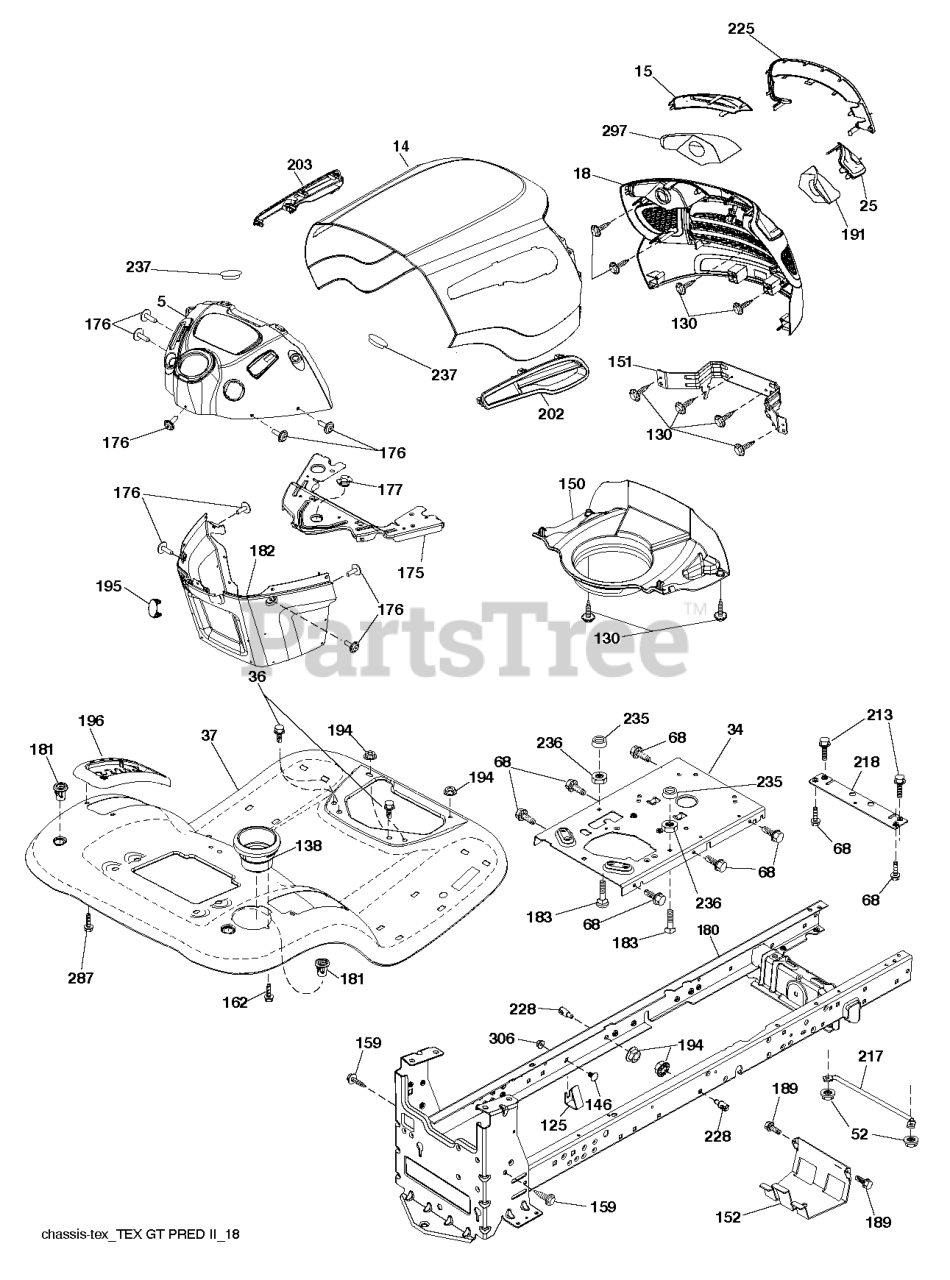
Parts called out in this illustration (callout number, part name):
5	DASH.UPPER.PREDATOR.M/C.BLACK
14	HOOD.PNT.PREDATOR.YT/GT.BLACK
15	LENS.MCCULLOCH.GT.LH
18	GRILLE.PREDGT2.GEN
25	LENS.MCCULLOCH.GT.RH
34	PLATE.ENGINE.WELDED.CHASSIS
36	SCREW 5/16"
37	FENDER.TLT.W/CPH.428
52	Locknut, Hex w/Insert 5/16-18 Unc
68	NUT 5/16C WHIZ
125	CLIP.FUEL.LINE
130	SCREW.#10 X 0.750.BOS (2 2)
138	CUPHOLDER.TL.TEX.BLACK
146	BOLT.RDHD.SHT.SQNK.3/8-16X5/8
150	AIR DUCT.HOOD.PRED YT/GT(2 2)
151	BRACKET.PIVOT.PREDATOR
152	SHIELD.BROWNING.W/TEX
159	SCREW, 3/8-16X3/4
162	Screw, Hex Wsh Hi-Lo 1/4-1/2 (AYP part number)
175	PLATE.PNT.CROSSMEMBER.HUSQ/PRE
176	SCREW.#10-24X5/8.RN.QU
177	BUSHING STEERING
180	CHASSIS
181	FEND/FTRST.PCH.CPH.NFW
182	DASH LOWER.HUSQ.PRED NO CRUISE
183	BOLT.5/16-18X1-1/4 FULL THD
189	SCREW
191	REFLECTOR.MCCULLOCH.GT.RH
194	NUT LOCK HEX FLANGE 5/16-18
195	PLUG.HOLE.DASH.LOWER.12V.BLK
196	CONSOLE.ASM.DECKLFT.BL/YBT.TLT
202	VENT.SIDE.HOOD.LH.PREDATOR.BLK
203	VENT.SIDE.HOOD.LH.PREDATOR
213	Bolt, Hex Head 5/16-18 UNC x 3/4 (AYP part number)
217	ROD.PIVOT.HOOD
218	X-PIECE.HOOD.STOP.NON/
225	TRIM.RING.MCCULLOCH.GT
228	STUD.FASTNER.W/ANTI-ROTATE
235	SPACER FENDER
236	NUT.CENTERLOCK.5/16-
237	PLUG.MOUNT.CARGO.BLK
287	SCREW 1/4X20
297	REFLECTOR.MCCULLOCH.GT.LH
306	NUT LOCK FLG 3/8-16 UNC
